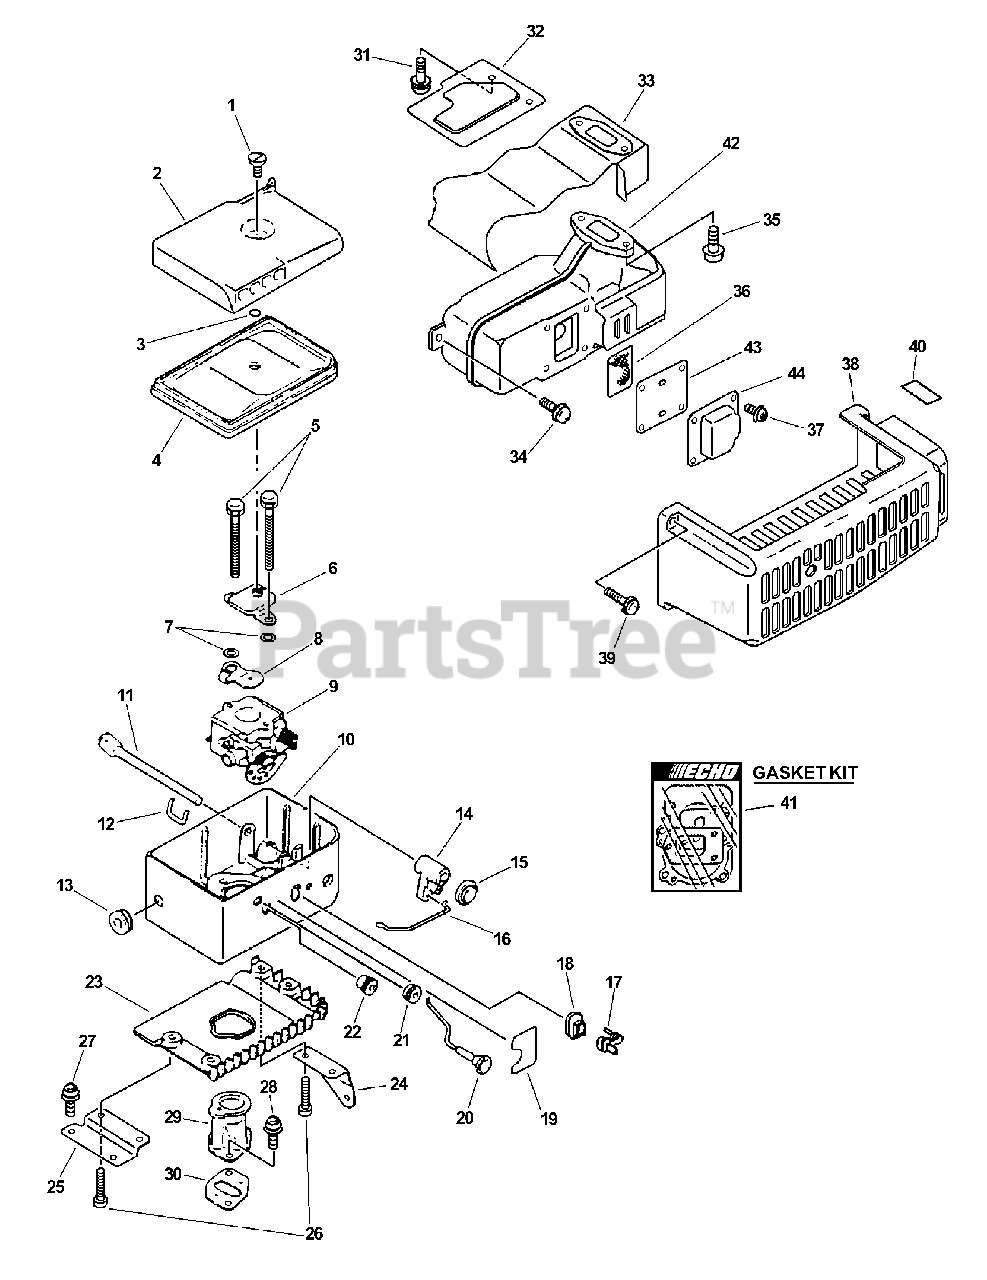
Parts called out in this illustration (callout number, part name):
2	COVER, AIR FILTER
3	O-RING 3
4	FILTER, AIR
5	SCREW 5×45
6	PLATE, PREVENT
7	WASHER 5.2×8×0.8T
8	SHUTTER, CHOKE
9	CARBURETOR - WT-409B
10	CASE, CARBURETOR
11	SHAFT, THROTTLE
12	CONNECTOR, THROTTLE
14	ARM, THROTTLE LEVER
15	HOLDER, THROTTLE LEVER
16	ROD, THROTTLE
17	GROMMET, PLUG
19	LABEL
20	ROD, CHOKE
22	GROMMET
23	INSULATOR
26	SCREW 5×25
27	SCREW 4×10
28	SCREW 5×14
29	ADAPTER, INTAKE
30	GASKET
31	SCREW 4×10
32	INSULATOR
33	GASKET, EXHAUST
34	SCREW 5×14
35	BOLT 5×16
36	SCREEN, SPARK ARRESTER
37	SCREW 4×10
38	COVER, MUFFLER
39	SCREW 5×20
40	LABEL, CAUTION - HOT
41	GASKET KIT
42	MUFFLER
43	GASKET, EXHAUST
44	GUIDE, EXHAUST
